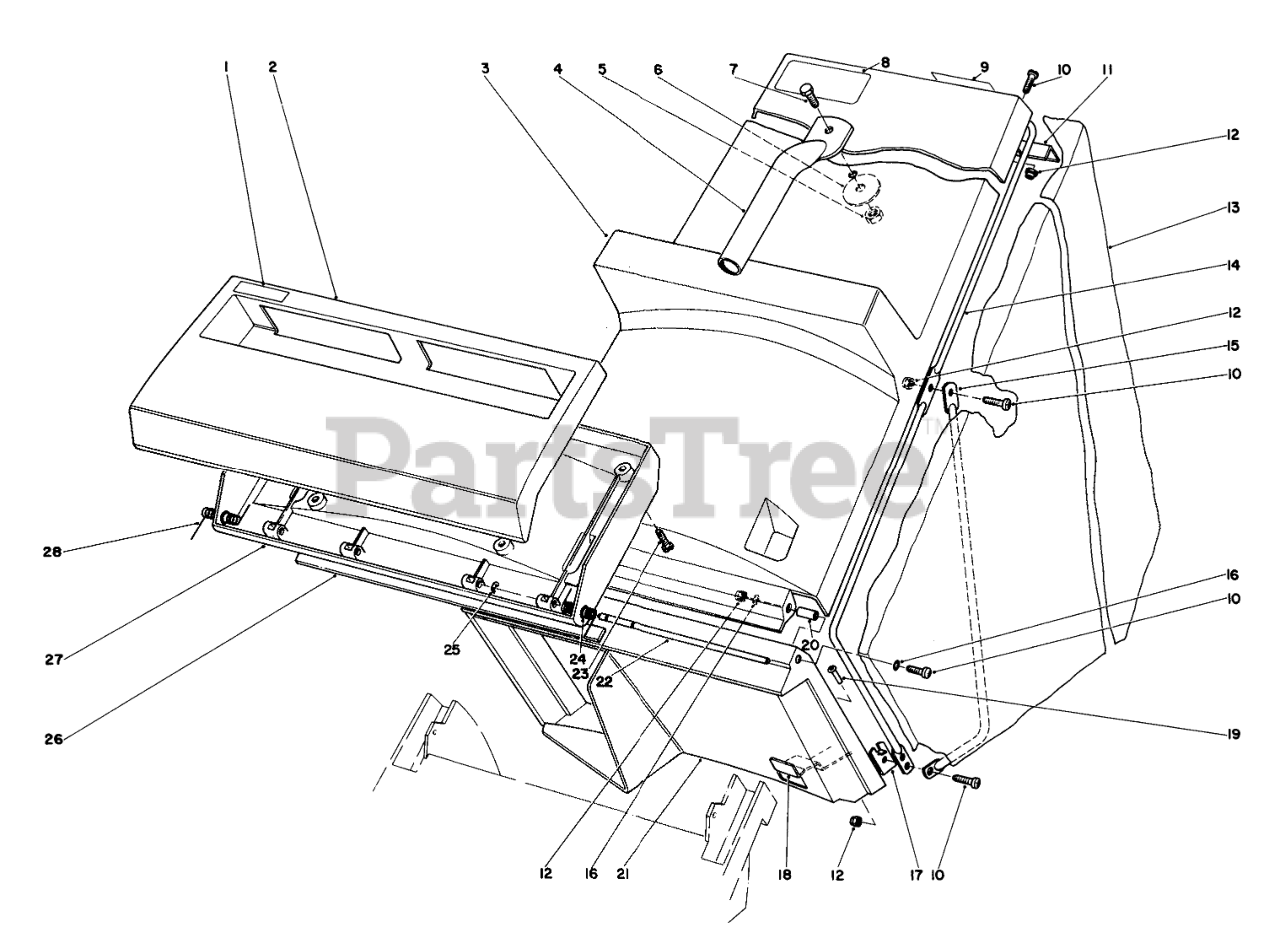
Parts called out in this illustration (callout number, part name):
1	Decal-Danger
2	Door Half-Outside
3	HOUSING-GRASS CATCHER
4	Handle-Grass Catcher
5	M6 X 1 LOCKNUT
6	WASHER-FLAT
7	M6 X 1 HEX HD CAPSCRW
8	Decal-Logo
9	Decal-Waming
10	SCREW-PPH
11	Hinge-Bracket
12	NUT-LOCK
13	BAG ASM
14	Bag Support-Upper
15	Bag Support-Lower
16	WASHER-FLAT
17	Bag Support-Front
18	DOOR LATCH
20	Spacer
21	DOOR GRASS CATCHER
22	Pin-Door Hinge
23	SCREW-PPH
24	LH TORSION SPRING
25	EXT RET E-RING
26	DOOR SEAL
27	DOOR HALF
28	TORSION SPRING RH
